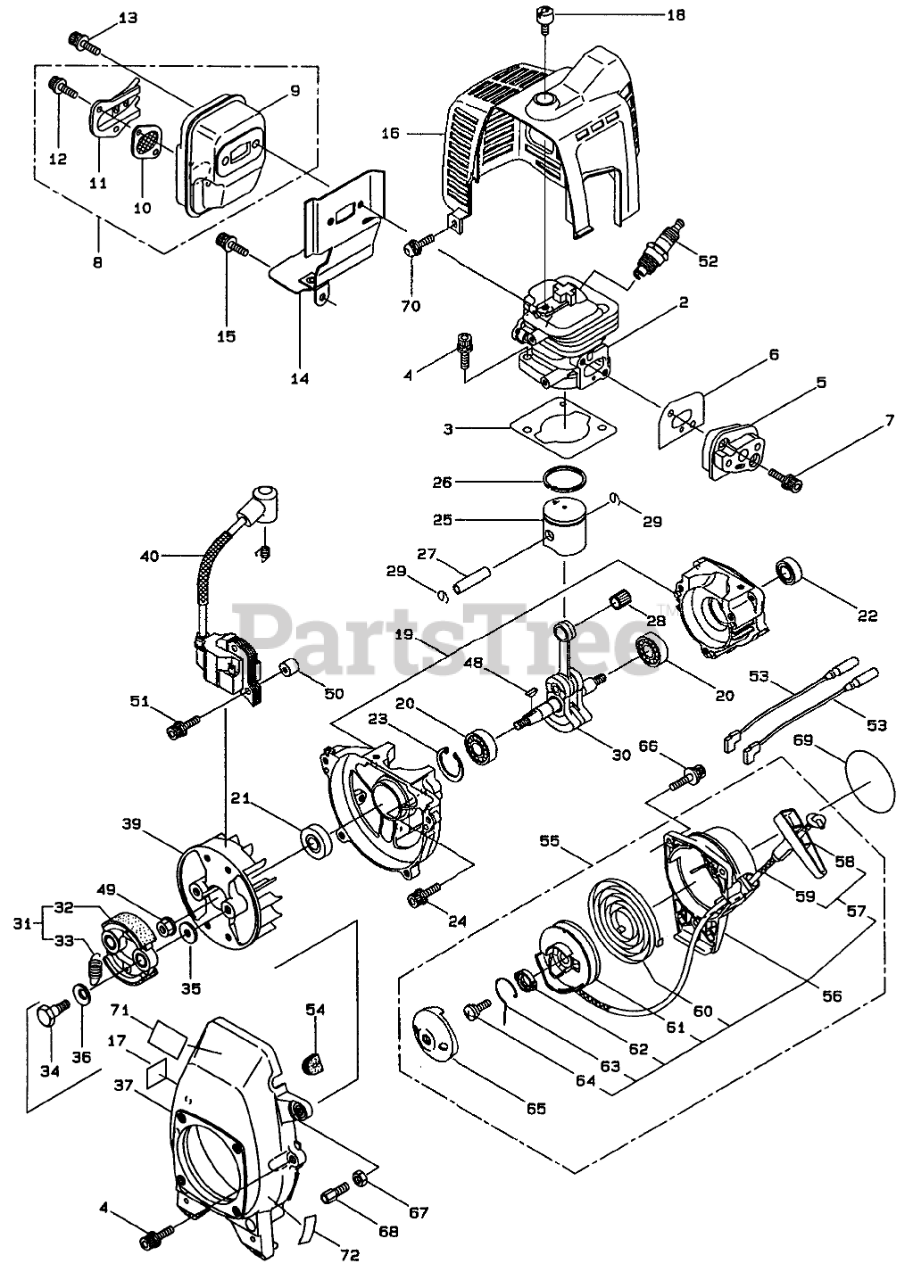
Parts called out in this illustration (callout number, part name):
2	CYLINDER
3	GASKET
5	INSULATOR
6	GASKET
7	SCREW
8	Muffler Asm (Incl. Ref. # 9-12)
9	Muffler Comp.
10	SPARK ARRESTOR
11	MUFFLER DEFLECTOR
12	CAPSCREW
13	SCREW
14	HEAT SHIELD
16	ENGINE SHROUD
17	DECAL
18	SCREW
19	CRANKCASE
20	BEARING
21	SEAL - OIL
22	SEAL - OIL
23	RING - SNAP
25	PISTON
27	PIN - PISTON
28	BEARING - NEEDLE
29	CIRCLIP
30	CRANKSHAFT ASSY
31	Clutch Asm (Incl. Ref. #32,33)
32	SHOE - CLUTCH
33	SPRING - CLUTCH
34	BOLT - CLUTCH
35	WASHER
36	WASHER - WAVE
37	Cover-Fan (Incl. Ref.#17)
39	FLYWHEEL
40	COIL ASSY
48	KEY - WOODRUFF
49	WASHER & NUT
50	SPACER
52	SPARK PLUG
53	SWITCH LEADS
54	GROMMET
55	Recoil Starter Asm (Incl. Ref. #56-65)
56	Recoil Asm. (Incl. Ref. #57-64)
57	Rope Asm (Incl. Ref. #58,59)
58	HANDLE
59	Rope-Starter
60	RECOIL SPRING
61	ROPE GUIDE
62	SPACER
63	RECOIL WIRE
64	SCREW
65	STARTER CUP
68	ADAPTER - SCREW
69	LABEL - ENGINE
70	SCREW
71	DECAL - TORO
72	DECAL
